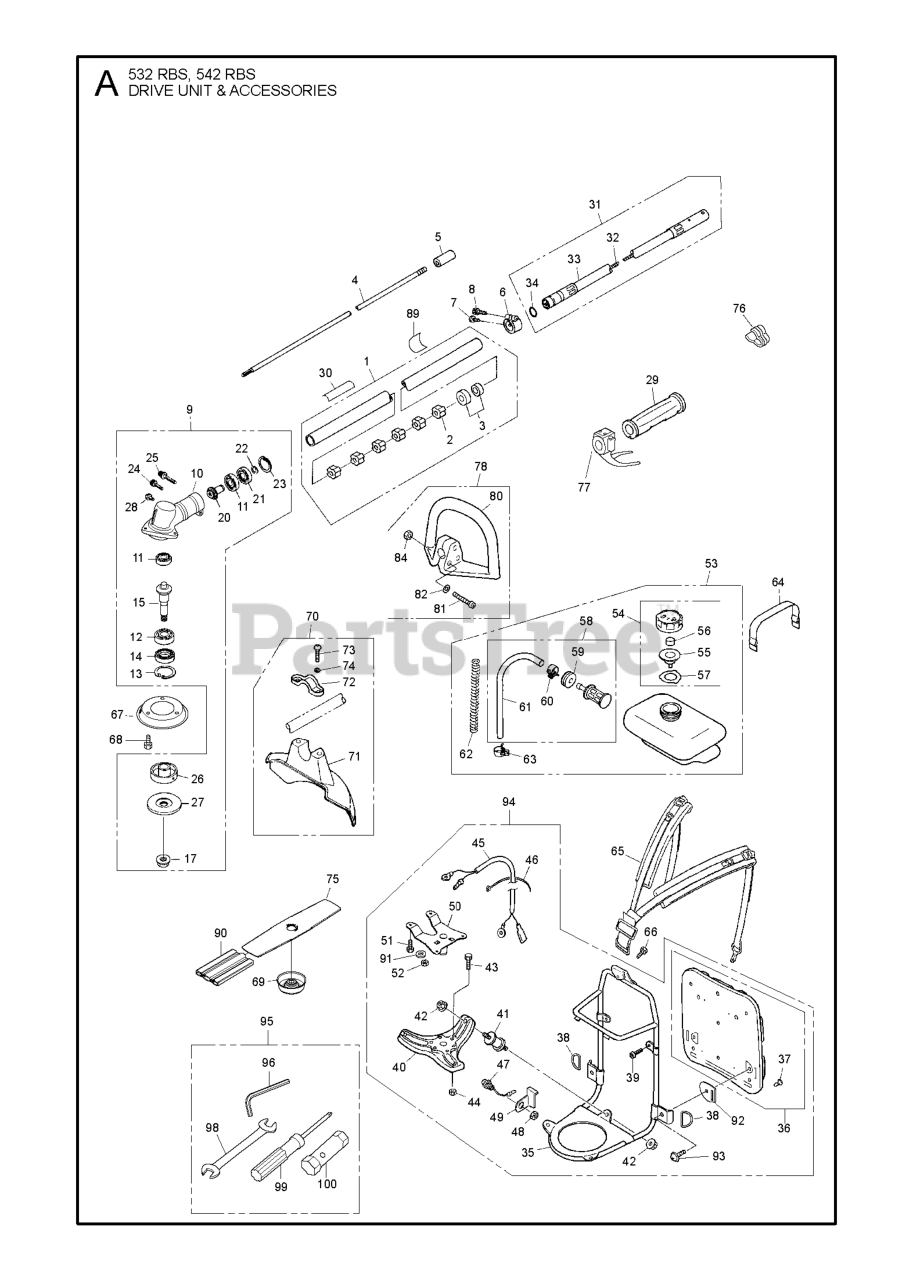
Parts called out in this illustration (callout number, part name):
1	PIPE COMP.(RPLS T321712100)
12	BEARING***
22	RING
23	RING,SNAP M26x1.2 RP-318013340
53	TANK ASSY
66	BOLT M5 X L10 ALLEN BOLT
68	BOLT M5 X L10 ALLEN BOLT
75	GRASS BLADE 1"
77	LEVER ASSY
81	SCREW 0026000530
98	WRENCH SPANNER
100	SOCKET.17X19
